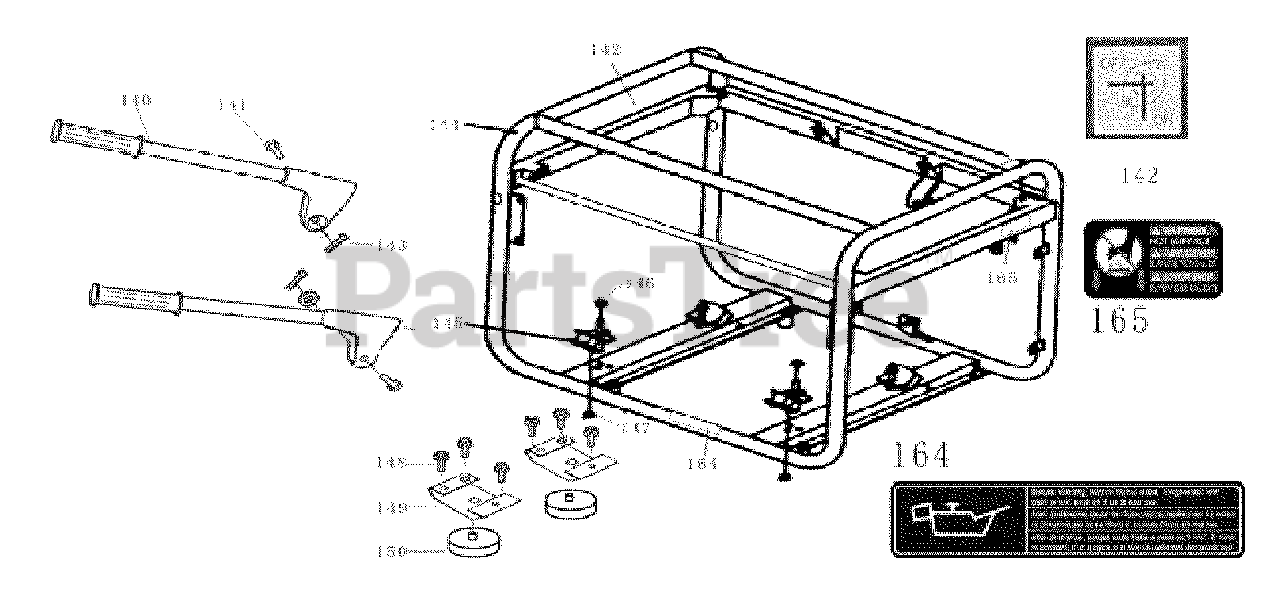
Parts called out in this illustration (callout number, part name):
141	Clievis pin
142	fuel gauge label
143	Cotter Pin
145	Motor mount
146	M10 flanged nut
148	M8x 16 pan head screw
149	Frame support
150	Frame support rubber
165	High temperture
